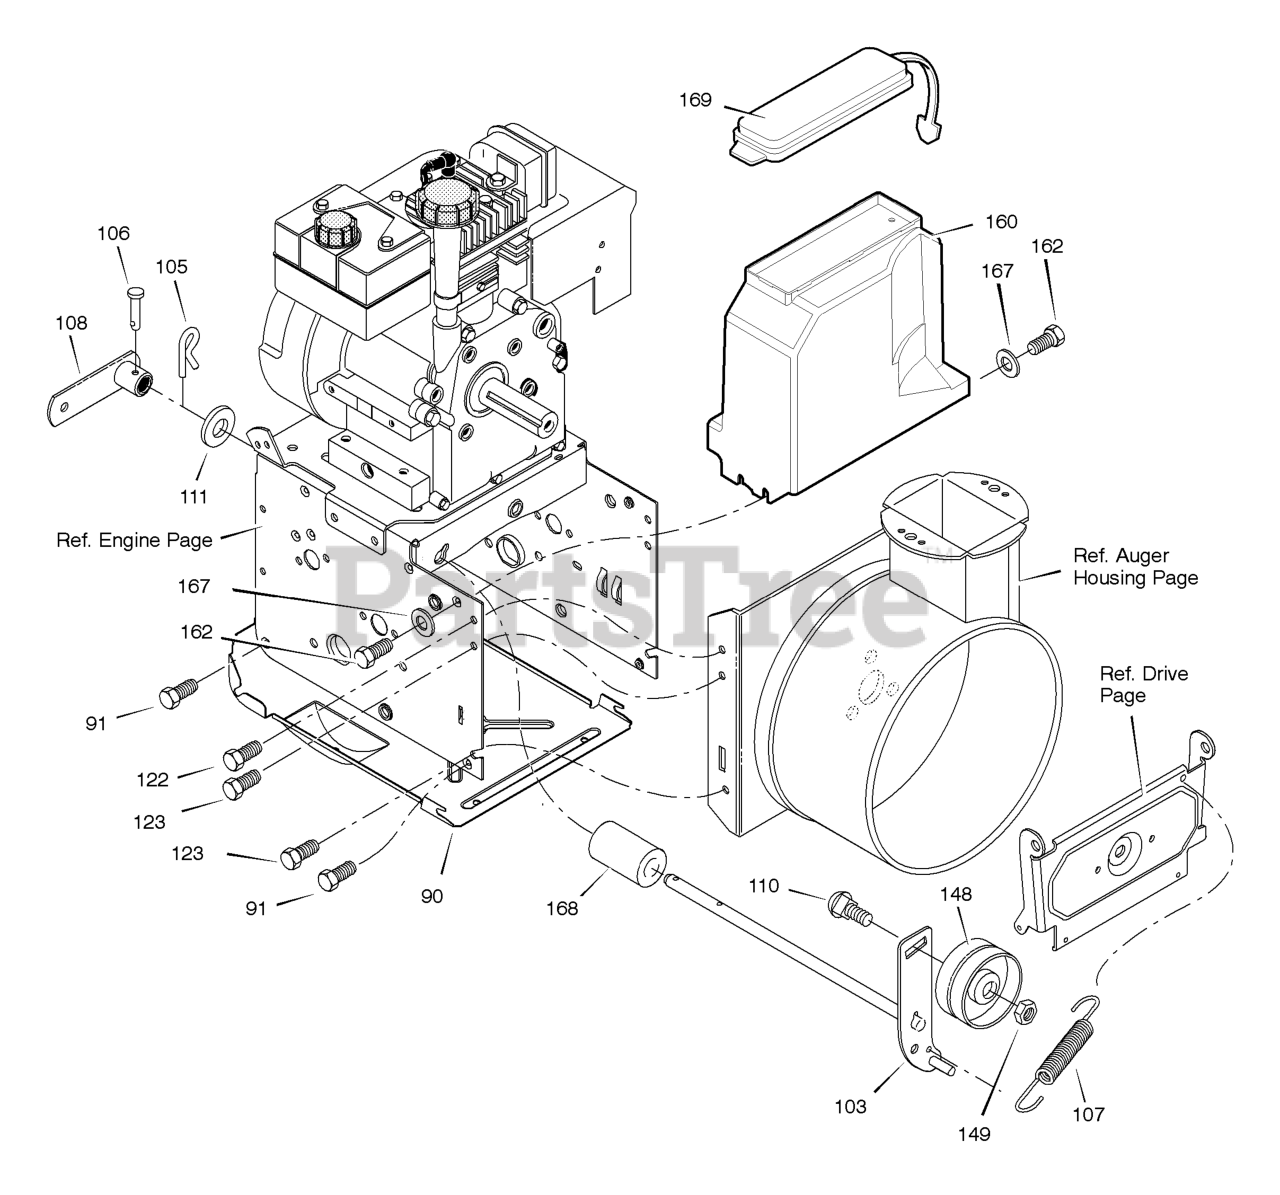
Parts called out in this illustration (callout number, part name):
90	COVER, BOTTOM
91	SCREW, 1/4-20X .63
103	IDLER ASSEMBLY, AUGER
105	PIN, HAIR .38DIAX1.64LG
106	PIN, CLEVIS 3/16" DIA
107	SPRING, TENSION
108	ASSY., SPRING ATTACH
110	BOLT, 3/8-16X1.25 CARR.
111	WASHER, FLAT
122	SCREW, TAP 5/16-18 X .50
123	SCREW, TAP 5/16-18 X .75
148	PULLEY, IDLER
149	NUT, JAM 3/8-16
160	COVER, BELT
162	SCREW, TAP
167	WASHER, FLAT
168	SPACER, AUGER BRACKET
169	LID, TOOL BOX
